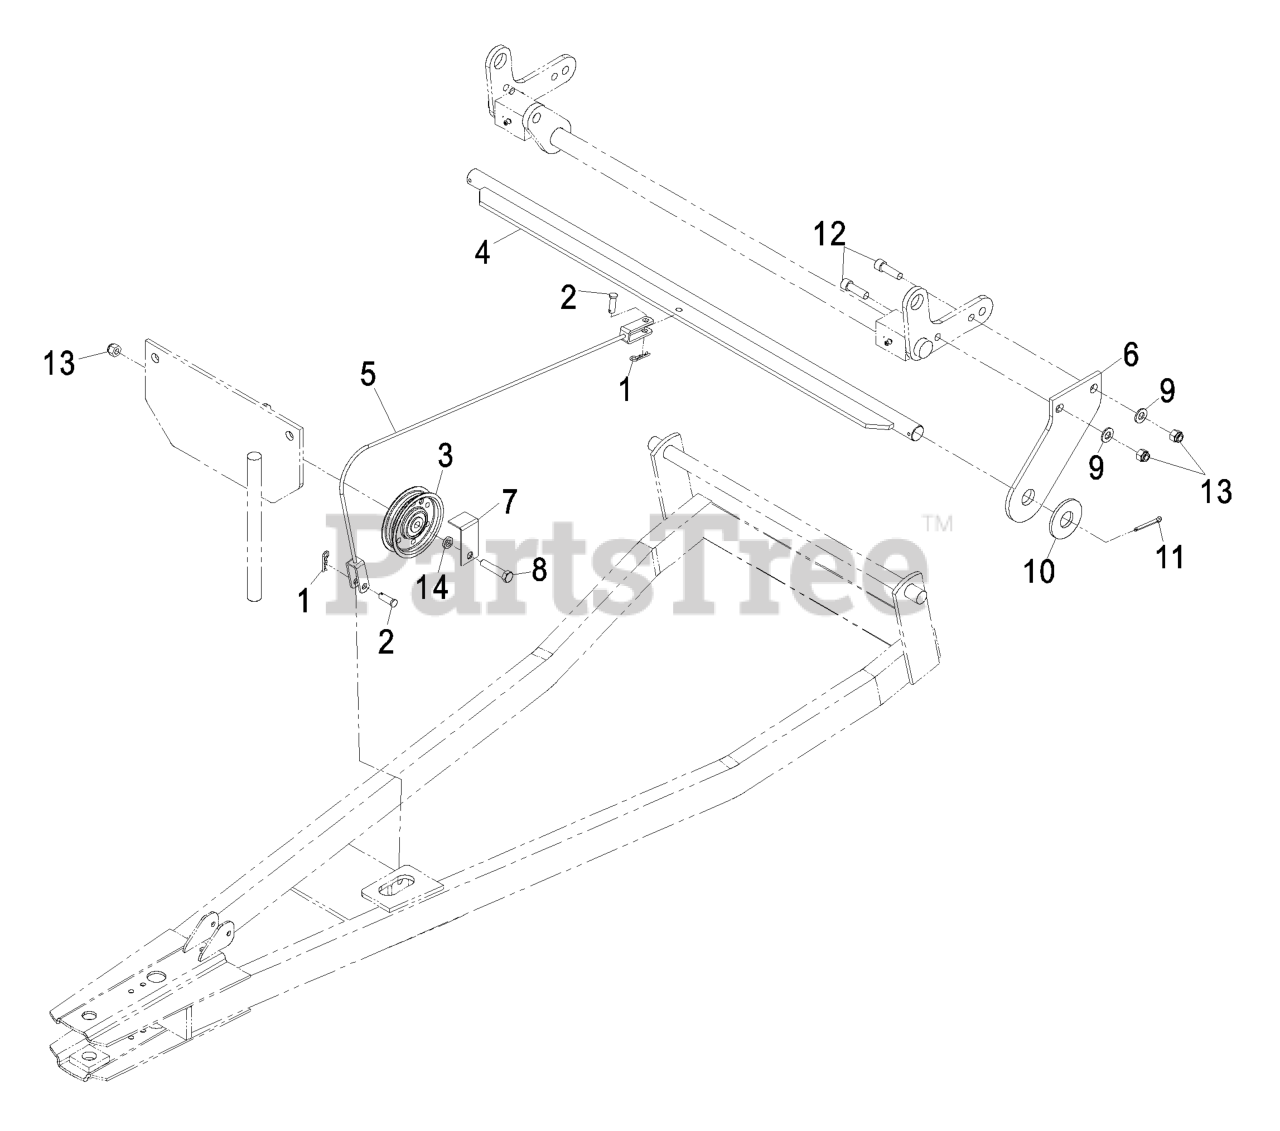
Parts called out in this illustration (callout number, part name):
1	PIN-COTTER
2	PIN-CLEVIS
3	PULLEY-IDLER, FLAT
5	CABLE,LIFT
6	ARM-LIFT
7	GUIDE-CABLE
8	SCREW-HH
9	WASHER-FLAT
10	WASHER-FLAT
11	PIN-COTTER
12	SCREW-HSH
13	NUT-LOCK, NI
14	SPACER
